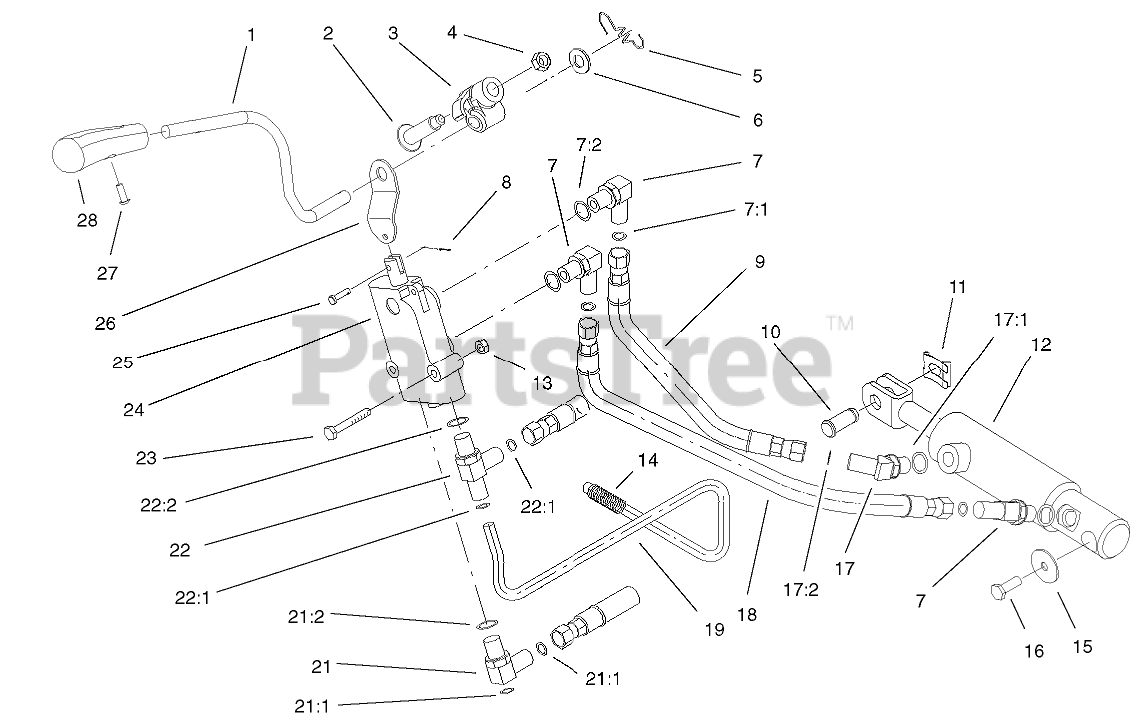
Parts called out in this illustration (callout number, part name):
1	HANDLE-LIFT
2	BOLT-SHOULDER
3	TRUNNION-LEVER, LIFT
4	NUT-JAM, LOCKING
5	SPRING-EXTENSION, LIFT
6	WASHER
7	FITTING-HYD, 90 DEGREE
7:1	O-RING
7:2	O-RING
8	PIN-COTTER
9	HOSE ASM
10	PIN-CLEVIS
11	CLIP-PIN
12	LIFT CYLINDER ASM
13	NUT-LOCK, NI
14	COVER-BRACE
15	WASHER-FLAT
16	SCREW-THREAD LOCKING
17	FITTING-HYD, 45 DEGREE
17:1	O-RING
17:2	O-RING
18	HOSE ASM
19	TUBE-HYD
21	FITTING-HYD, 90 DEGREE
21:1	O-RING
21:2	O-RING
22	FITTING-HYD, TEE
22:1	O-RING
22:2	O-RING
23	SCREW-HH
24	VALVE-HYD
25	PIN-CLEVIS
26	LINK-LIFT
27	SCREW-PPHTF
28	Knob-Lift (only on: 73547)
28	Knob-Lift (only on: 73580)
